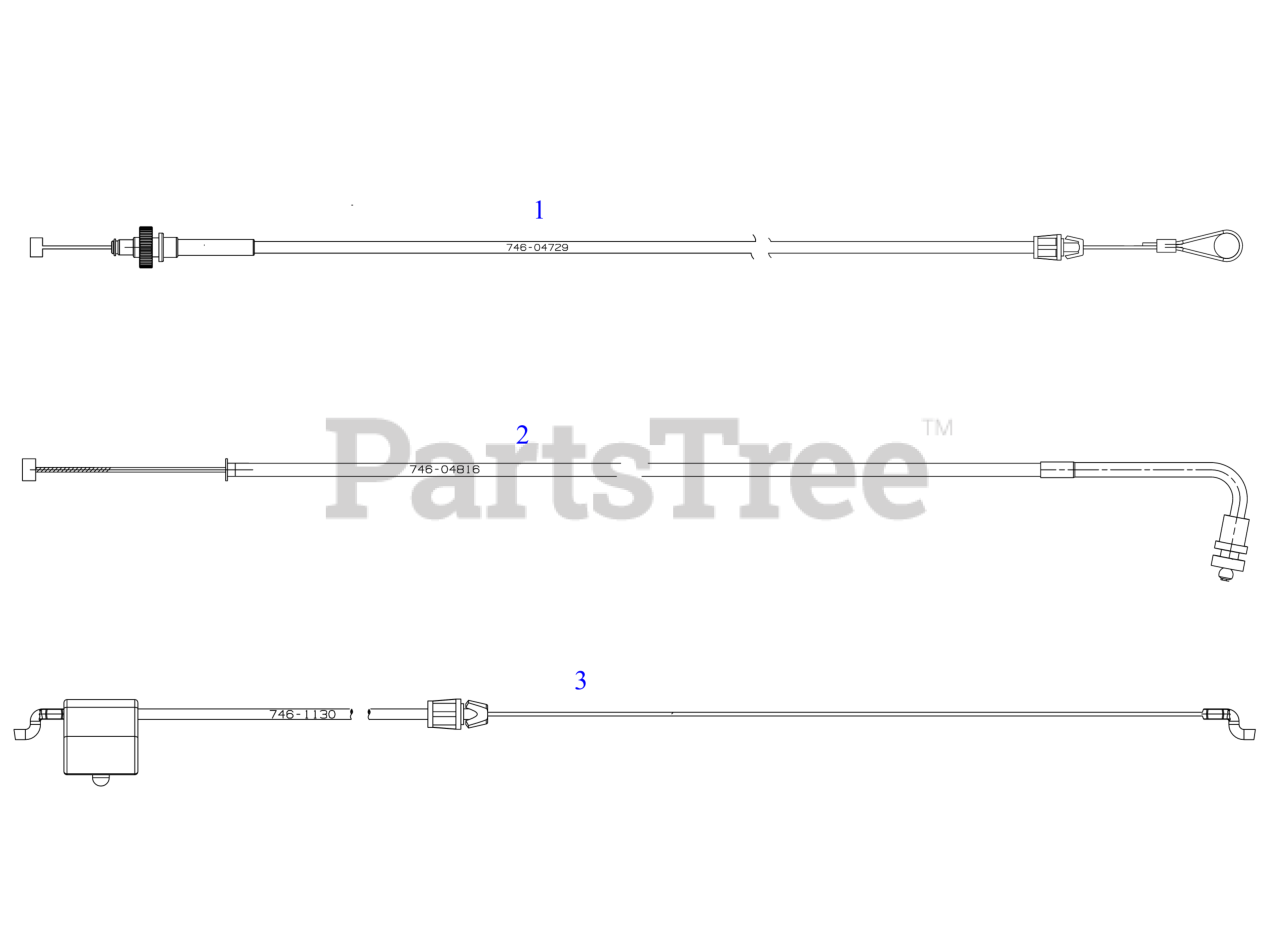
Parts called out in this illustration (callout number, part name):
1	SPEED ADJUSTMENT CABLE 56.25"
2	SPEED SELECT CABLE W/ELBOW
3	CONTROL CABLE 40"
